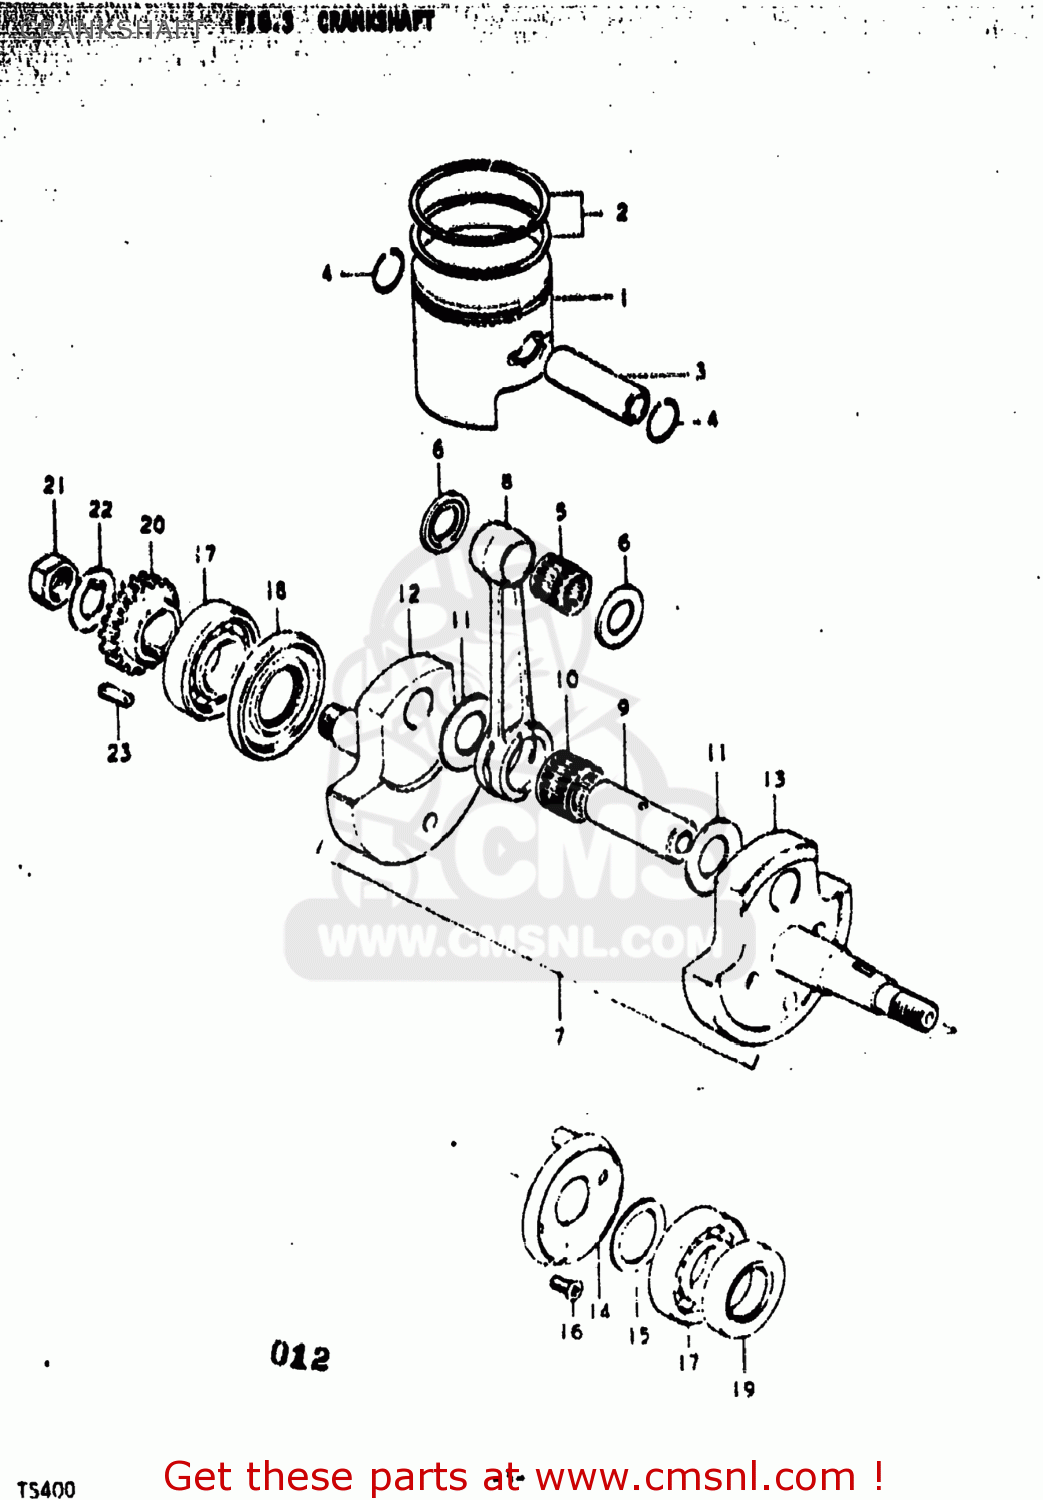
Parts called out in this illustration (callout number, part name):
1	PISTON
2	RING SET,PISTON
3	PIN,PISTON
4	CIRCLIP
5	BEARING
6	WASHER
7	CRANKSHAFT SET
8	CONNECTING ROD
9	PIN,CRANK
10	BEARING
11	WASHER
12	CRANKSHAFT
13	CRANKSHAFT,LEFT
14	PLATE,CRANKSHAFT OIL GUIDE
15	WASHER
16	SCREW
17	BEARING
18	OIL SEAL
19	OIL SEAL
20	GEAR,PRIMARY DRIVE
21	NUT (20MM)
22	WASHER
23	KEY
